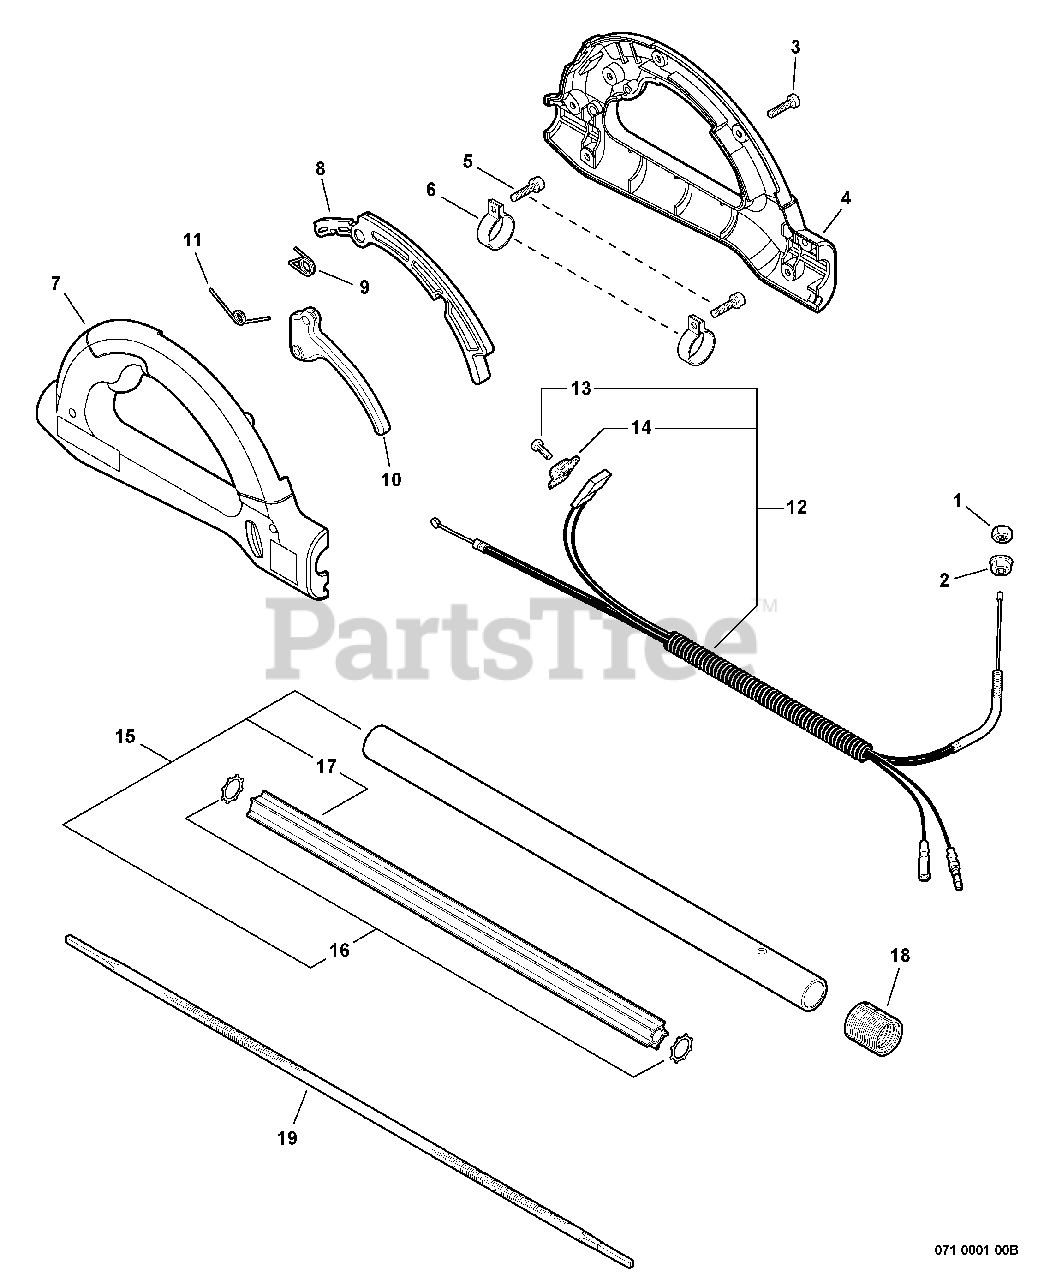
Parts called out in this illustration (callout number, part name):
2	NUT - 6 -- FLANGE
3	SCREW - 5X18
4	HANDLE - RIGHT
5	SCREW - 5X20
7	HANDLE - LEFT
8	LEVER, TRIGGER LOCKOUT
9	SPRING, LOCKOUT LEVER
10	TRIGGER, THROTTLE
11	SPRING, TRIGGER
12	CONTROL CABLE ASSY
13	SCREW - 3X10
14	KNOB, SWITCH - ORANGE
15	PIPE ASSY
18	TUBE, PROTECTIVE - CORRUGATED
19	DRIVESHAFT - FLEXIBLE
